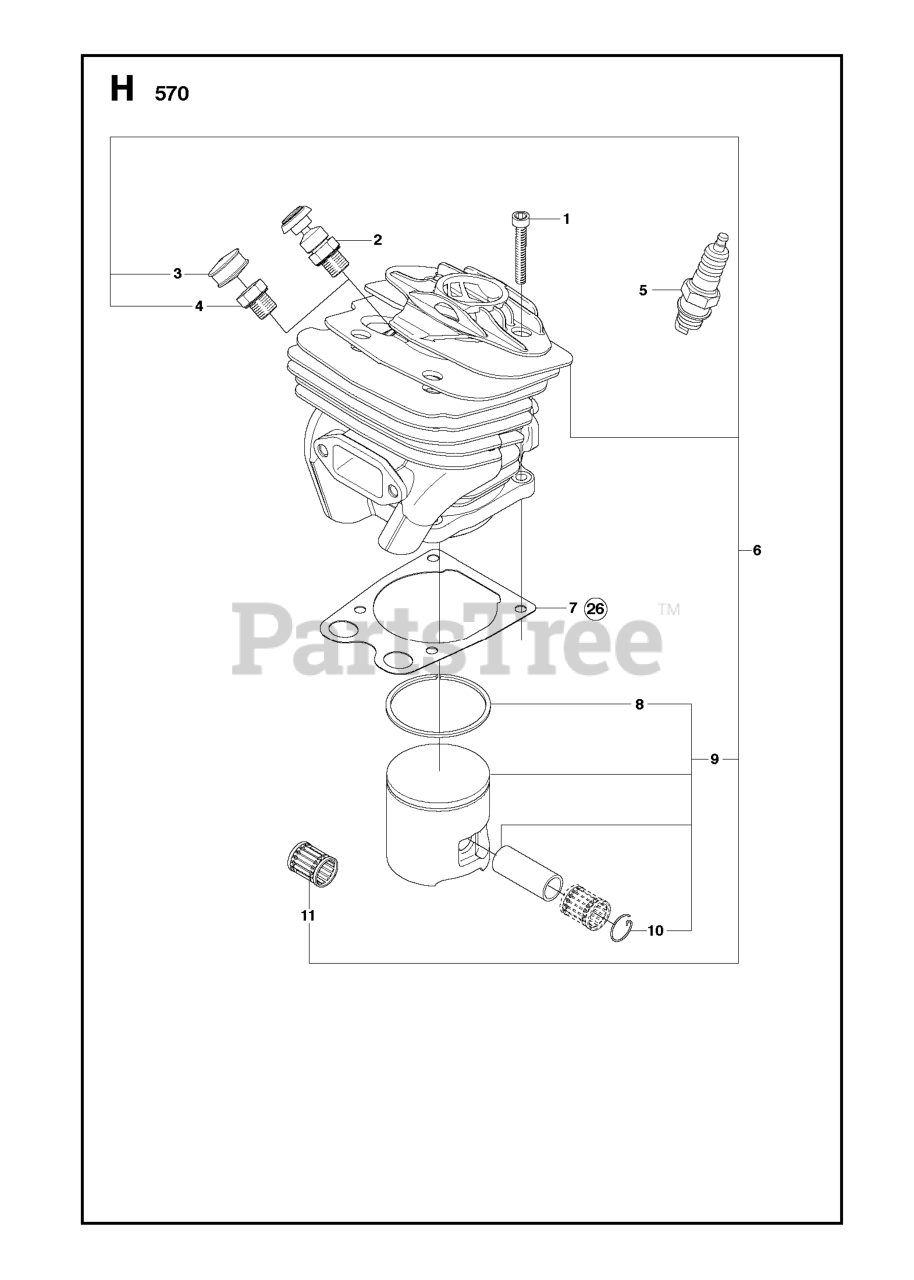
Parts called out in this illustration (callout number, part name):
1	SCREW MC6S 5X25
4	CYLINDER PLUG
5	SPARK PLUG M14X1.25 NGK BPMR7A
8	PISTON RING
9	PISTON 49 MM
10	WRIST PIN CLIP
11	NEEDLE BEARING PISTON PIN 12X1
26	GASKET SET
